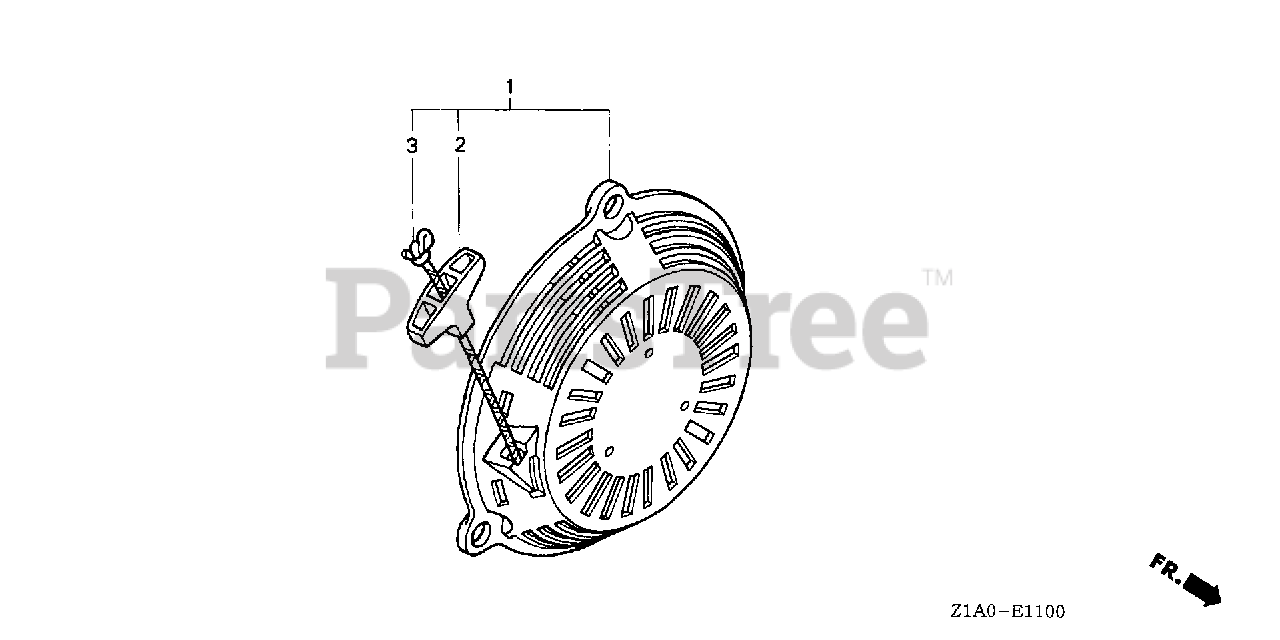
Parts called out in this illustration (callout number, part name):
1	STARTER ASSY., RECOIL *NH1* (BLACK)
1	STARTER ASSY., RECOIL *R280* (POWER RED)
2	KNOB, RECOIL STARTER
3	ROPE, RECOIL STARTER (#3.5X52")
